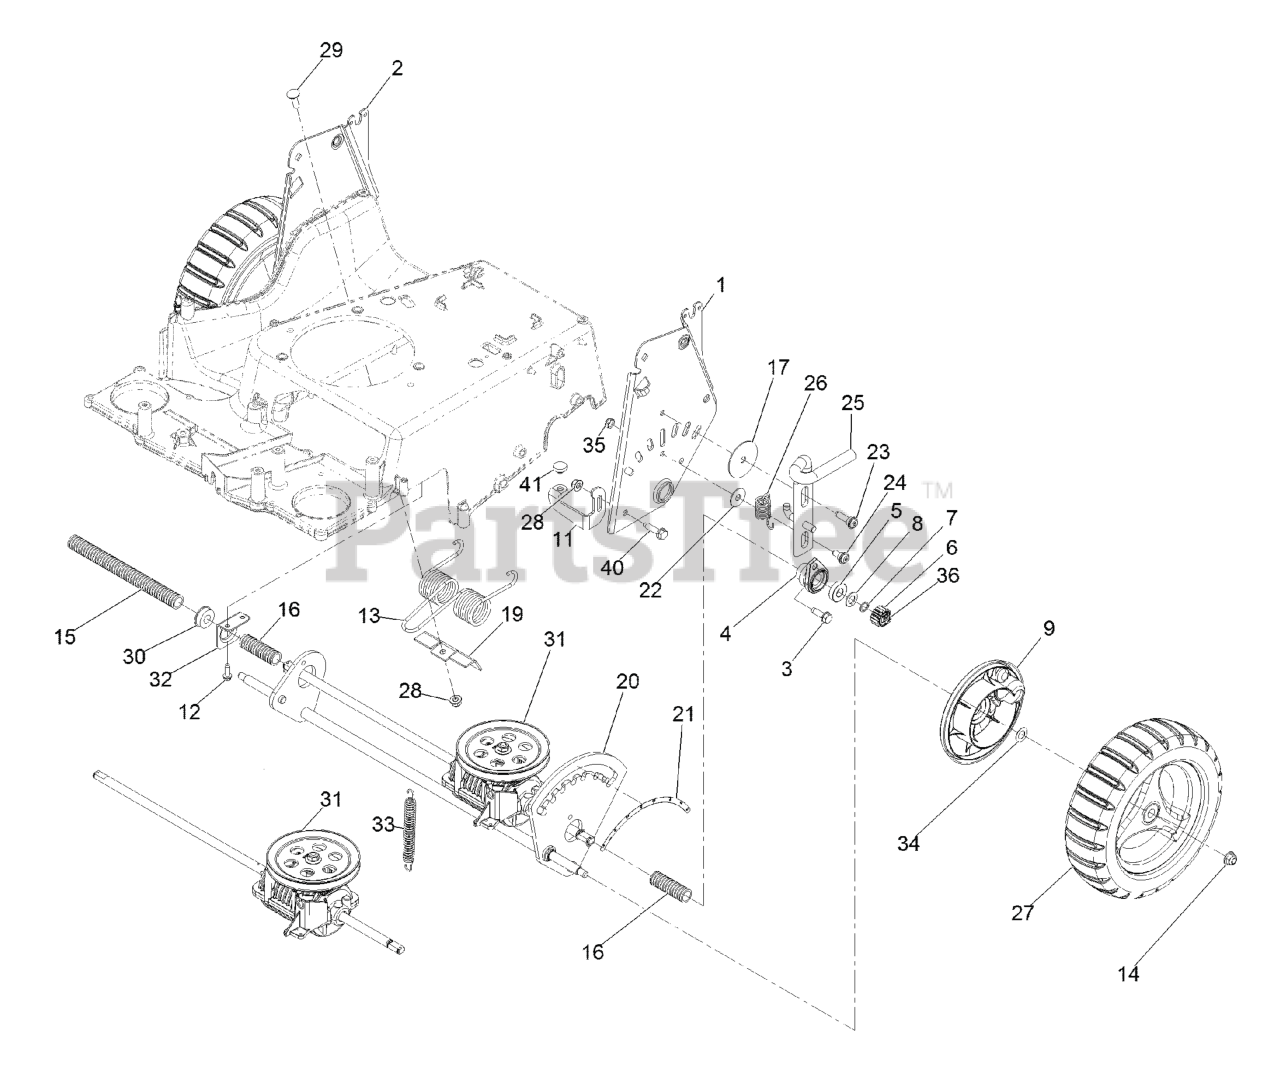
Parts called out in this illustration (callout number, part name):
1	LH HOC PLATE ASM
2	RH HOC PLATE ASM
3	SCREW-THD ROLL, HWH
4	RETAINER-BEARING
5	BEARING-BALL
6	GEAR-PINION, 15T
7	RING-RETAINING
8	WASHER-THRUST
9	COVER,GEAR
11	BRACKET-STOP, ADJUSTABLE
12	SCREW-HWHTF
13	SPRING-TORSION
14	NUT-HF, NI
15	CONDUIT-CONVOLUTED
16	CONDUIT-CONVOLUTED
17	WASHER-PLAIN
19	BRACKET
20	AXLE-REAR
21	DECAL-HOC, REAR
23	SCREW-SHOULDER, BHTF
24	BOLT-SHOULDER
25	LOCK-HEIGHT, ADJUST
26	SPRING-EXTENSION
27	WHEEL ASM, 10.5 W/GEAR
28	NUT-HF, NI
29	BOLT-CARR
30	BEARING-BALL
31	TRANSMISSION KIT
31:2	PIN-SNAP
31:3	RING-RETAINING
33	SPRING-EXTENSION
34	WASHER-PLAIN
35	NUT-LOCK, NI
36	PIN-SNAP
40	SCREW-HWHTF
